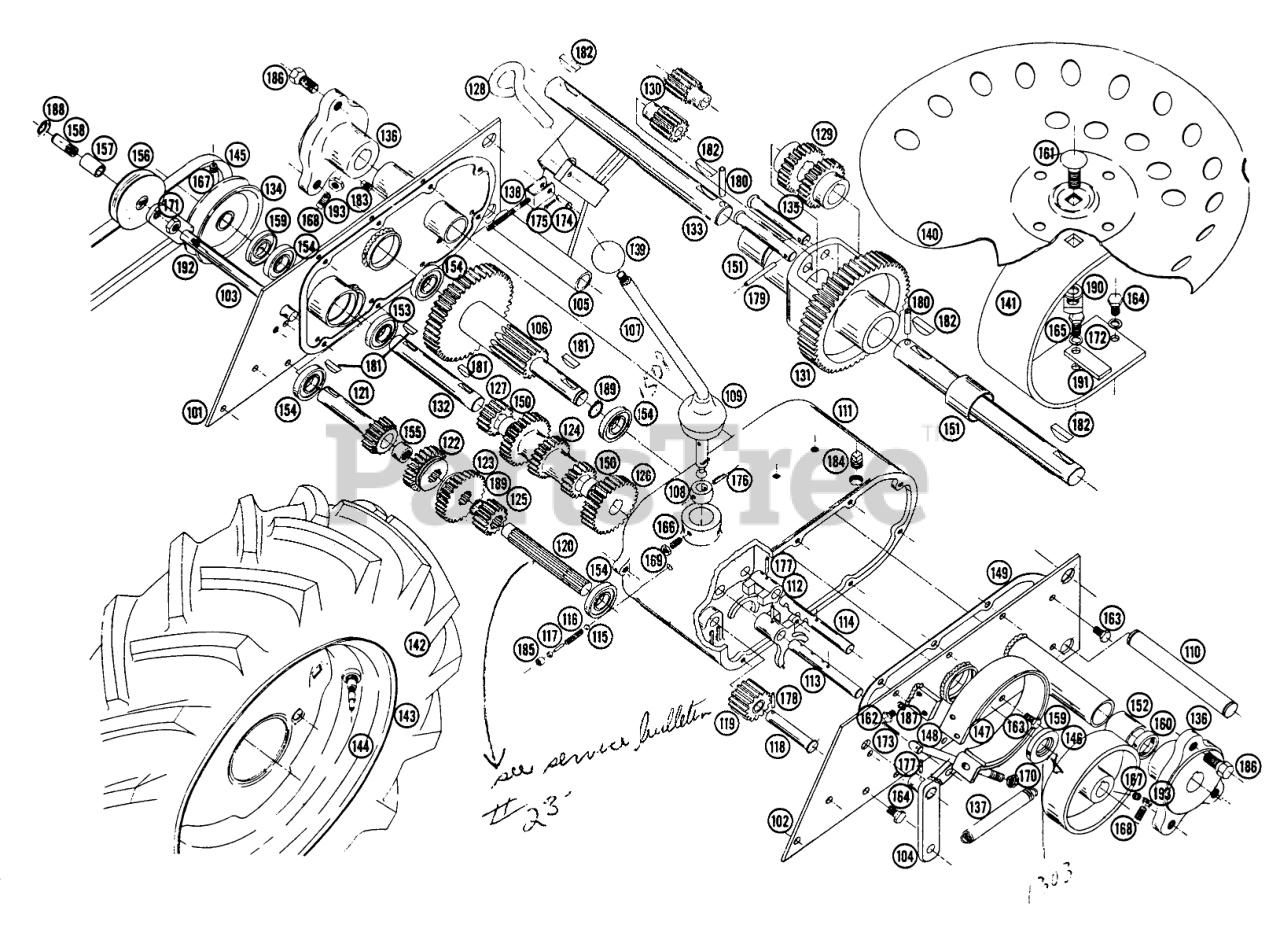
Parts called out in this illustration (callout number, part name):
101	Right Trans. Cover
102	Left Trans. Cover
103	Idler Arm
105	Hitch
109	COVER-DUST
110	Hitch Pin
111	Trans. Hsg
112	FORK-SHIFT
115	BALL-DETENT
119	Rev. Idler Gear
120	Spline Shaft
125	GEAR
126	GEAR-CLUSTER SHAFT
132	Cluster Shaft
134	PULLEY
141	Seat Spring
142	T T Assembly
144	Rim
146	Brake Drum
148	Brake Rod
150	BUSHING-BRONZE
155	BEARING-NEEDLE
157	Bronze Bearing
158	Stud-Idler Pin
161	Carriage Bolt
162	Hex Head Cap
163	Hex Head Cap
164	Hex Head Cap
165	Hex Head Cap
166	SETSCREW
167	Snap Ring
168	Set Screw Sq. Head
170	Hex Nut
172	Lockwasher
173	Cotter Key
175	Cotter Pin
176	Roll Pin
177	Roll Pin
179	RoIl Pin
180	31500 1967 OPC
182	Woodruff Key #15
183	Pipe Plug
185	CUP-PLUG
187	Lockwasher, 1/4
188	Snap Ring
190	Lockwasher
191	Lug-Cable
193	31300 '65-67&UP 20
